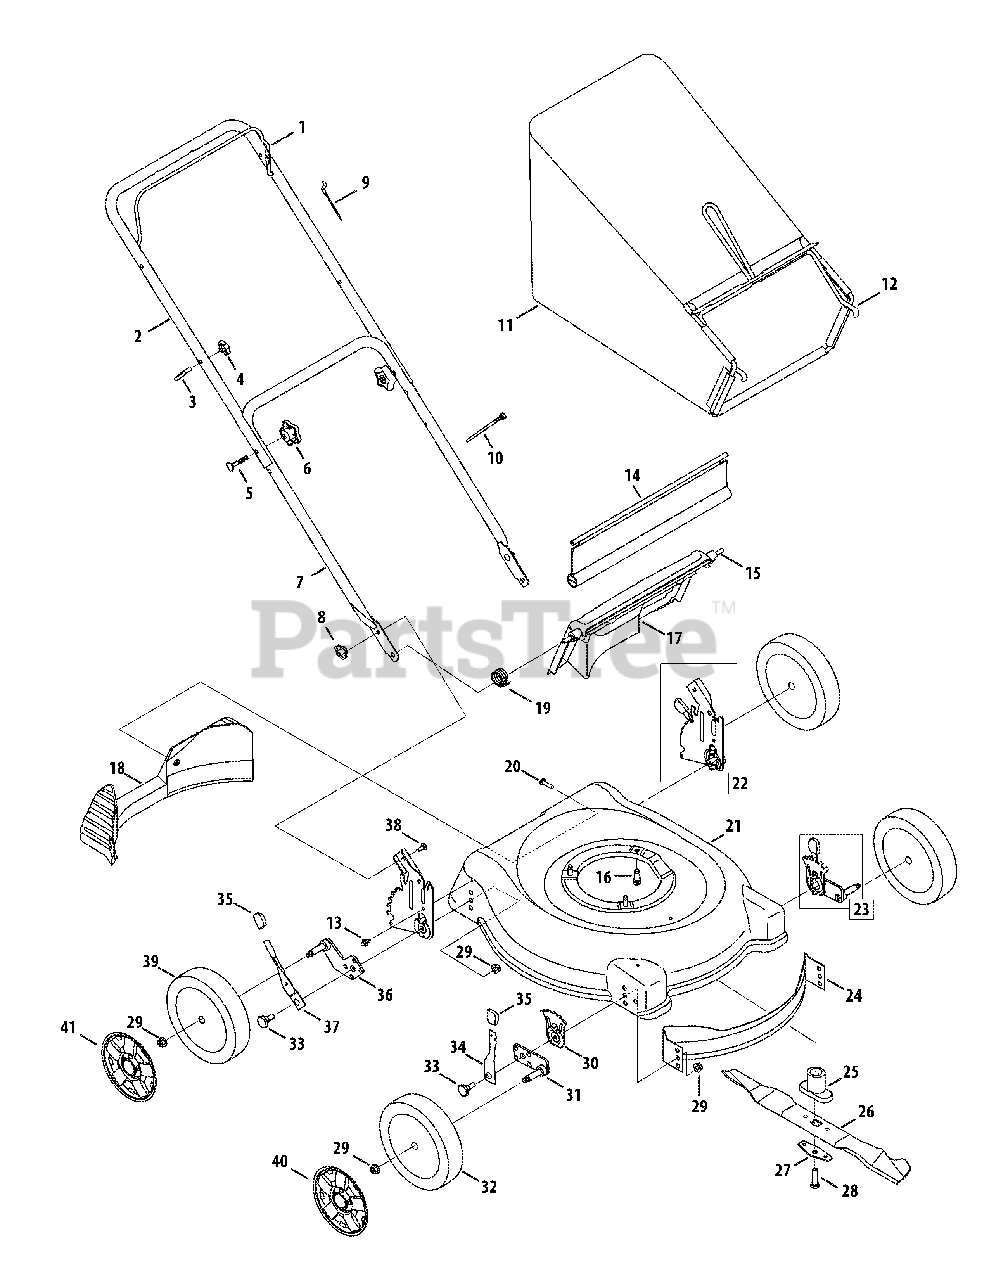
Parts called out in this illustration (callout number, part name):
1	Blade Control
2	Upper Handle
3	Rope Guide
4	Wing Nut, 1/4-20
5	Carriage Bolt, 5/16-18 x 2
6	Hand Star Knob
7	Lower Handle
8	Wing Nut, 1/4-20
9	Control Cable
10	Cable Tie
11	Grass Bag
12	Grass Bag Frame
13	Screw, 1/4-20 x .625
14	Trailshield
15	Rear Door Pivot Rod
16	TT Screw, 3/8-16 x 1
17	Rear Discharge Door
18	Rear Baffle
19	Torsion Spring RH
20	Screw, 1/4-15 x 1.00
21	Deck, 21 inch
22	Handle Bracket Assy - RH
22	Handle Bracket Assy - LH
23	Ht. Adj. Assy. Frt - LH
23	Ht. Adj. Assy. Frt - RH
24	Front Baffle
25	Blade Adapter, #6 x 2.15
26	Mulch Blade
27	Blade Bell Support
28	Screw, 3/8-24 x 2.50
29	Flange Lock Nut, 3/8-16
30	Height Adjustment Plate
31	Pivot Arm Assembly RH
31	Pivot Arm Assembly LH
32	Front Wheel
33	Shoulder Screw
34	Spring Lever
35	Height Adjustment Knob
36	Pivot Arm Assembly - RH
36	Pivot Arm Assembly - LH
37	Spring Lever
38	Carriage Bolt, 1/4-20
39	Rear Wheel
40	Hub Cap - Front
41	Hub Cap - Rear
